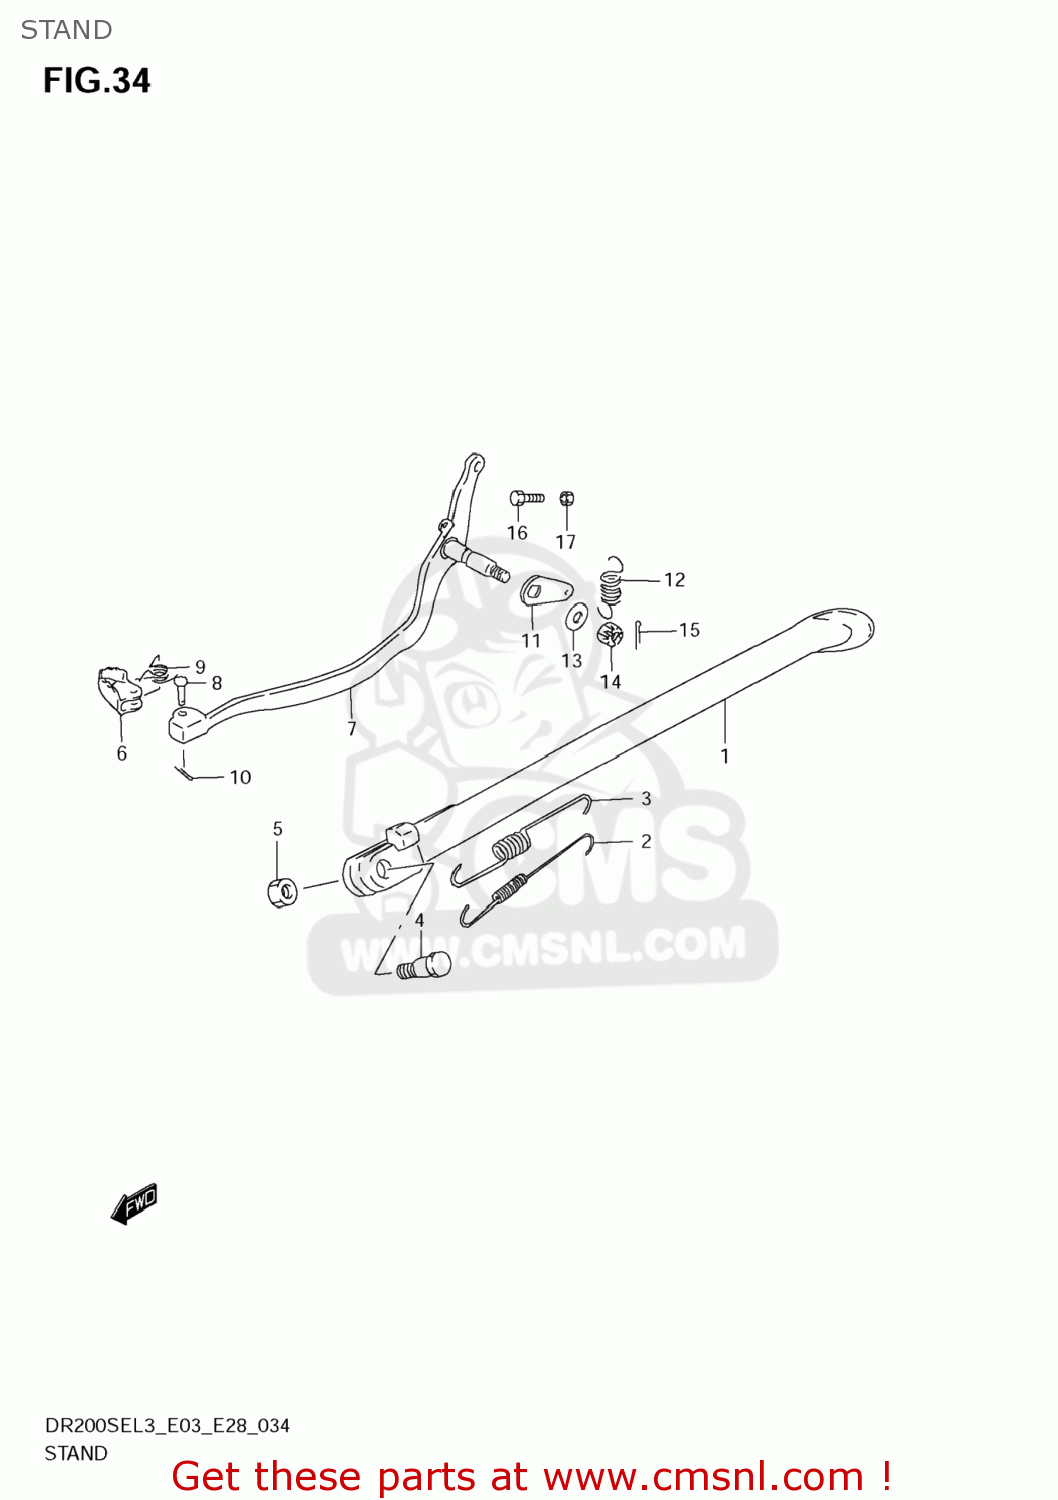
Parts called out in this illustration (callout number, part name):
1	STAND,PROP(BLACK)
2	SPRING
3	SPRING
4	BOLT(10X30)
5	NUT
6	PEDAL,BRAKE
7	ARM,BRAKE PEDAL
8	PIN
9	SPRING
10	PIN
11	ARM,BRAKE RETURN SPRING
12	SPRING
13	WASHER
14	NUT
15	PIN
16	BOLT(6X23)
17	NUT
